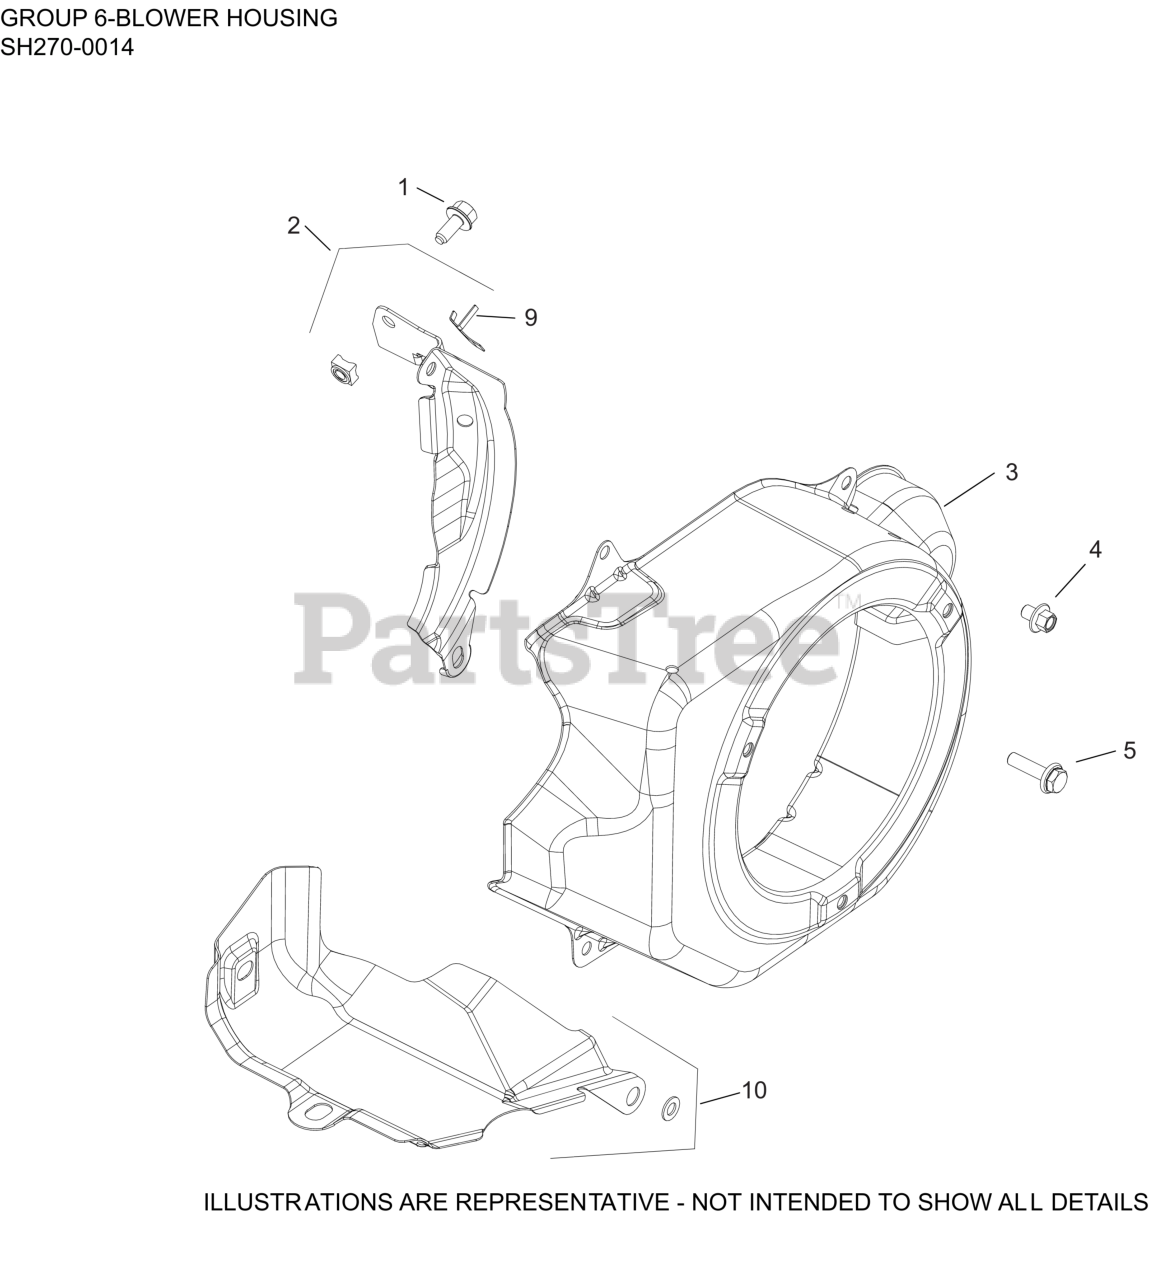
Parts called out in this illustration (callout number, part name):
1	SCREW, HEX FLANGE (M6)-USE 25 086 433-S
1	SCREW, HEX FLANGE (M6)
2	COVER, HOUSING LOWER BLOWER ASSEM
3	HOUSING, BLOWER ASSEMBLY
4	SCREW, M6 X 8 HEX FLANGE HEAD
5	SCREW, M6 X 22
9	CLIP, WIRE HARNESS-DISCONTINUED
10	KIT, CYLINDER SHIELD
